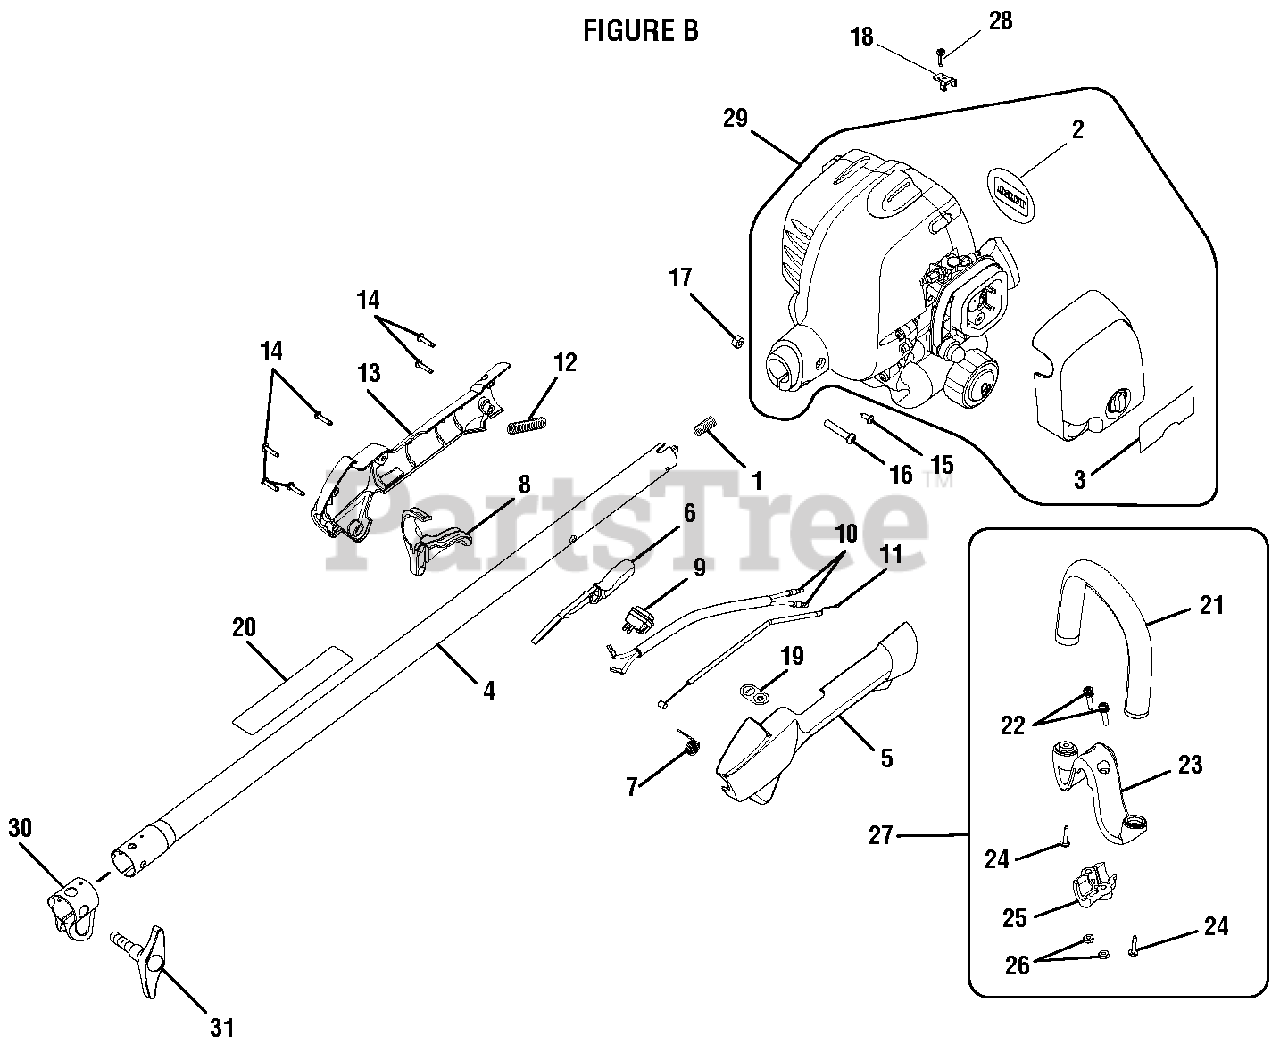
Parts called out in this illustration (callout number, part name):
1	Compression Spring
2	Logo plate
3	Lower Start Label
4	Upper Shaft Assembly
5	Rear Handle Support
6	Lock-off Button
7	Trigger Spring
8	Trigger
9	On/Stop Switch
11	Cable, Throttle
12	Corrugated Tube
13	Rear Handle Cover
14	Screw (M4 x 16 mm)
15	Screw (#8-16 x 1/2 in. Tri-Lobular)
16	Screw (M6 x 1-30 mm)
17	Hex Nut (M6.3 x 1)
18	Throttle Cable Clamp
19	On/Stop Label
20	Warning Label
21	Front Handle w/Grip
22	Slotted Torx (#12-24 x 1 in.)
24	Screw (10-14 x 1 in.)
25	Clamp
26	Hex Nut (12-24)
27	Front Handle Assembly
28	Screw (M4 x 16 mm)
29	Powerhead Assembly
30	Boom Clamp
